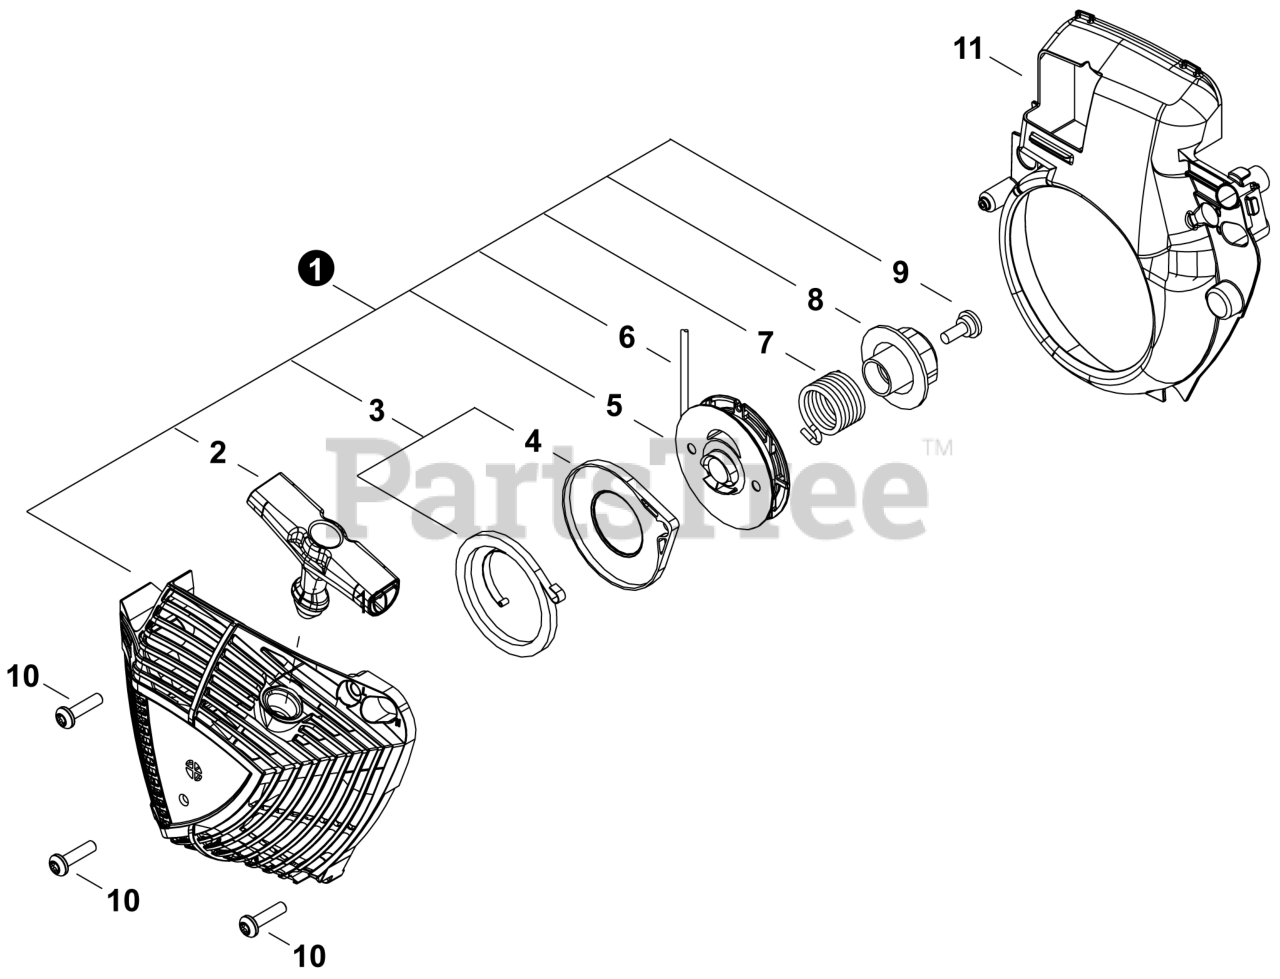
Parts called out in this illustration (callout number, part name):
1	STARTER ASSY, RECOIL
2	GRIP, STARTER
3	SPRING KIT, RECOIL
4	SPRING CASE
5	REEL, ROPE
6	ROPE, STARTER
7	SPRING, TORSION
8	PAWL CATCHER
9	SCREW
10	BOLT, TORX 5x20
11	COVER, FAN
